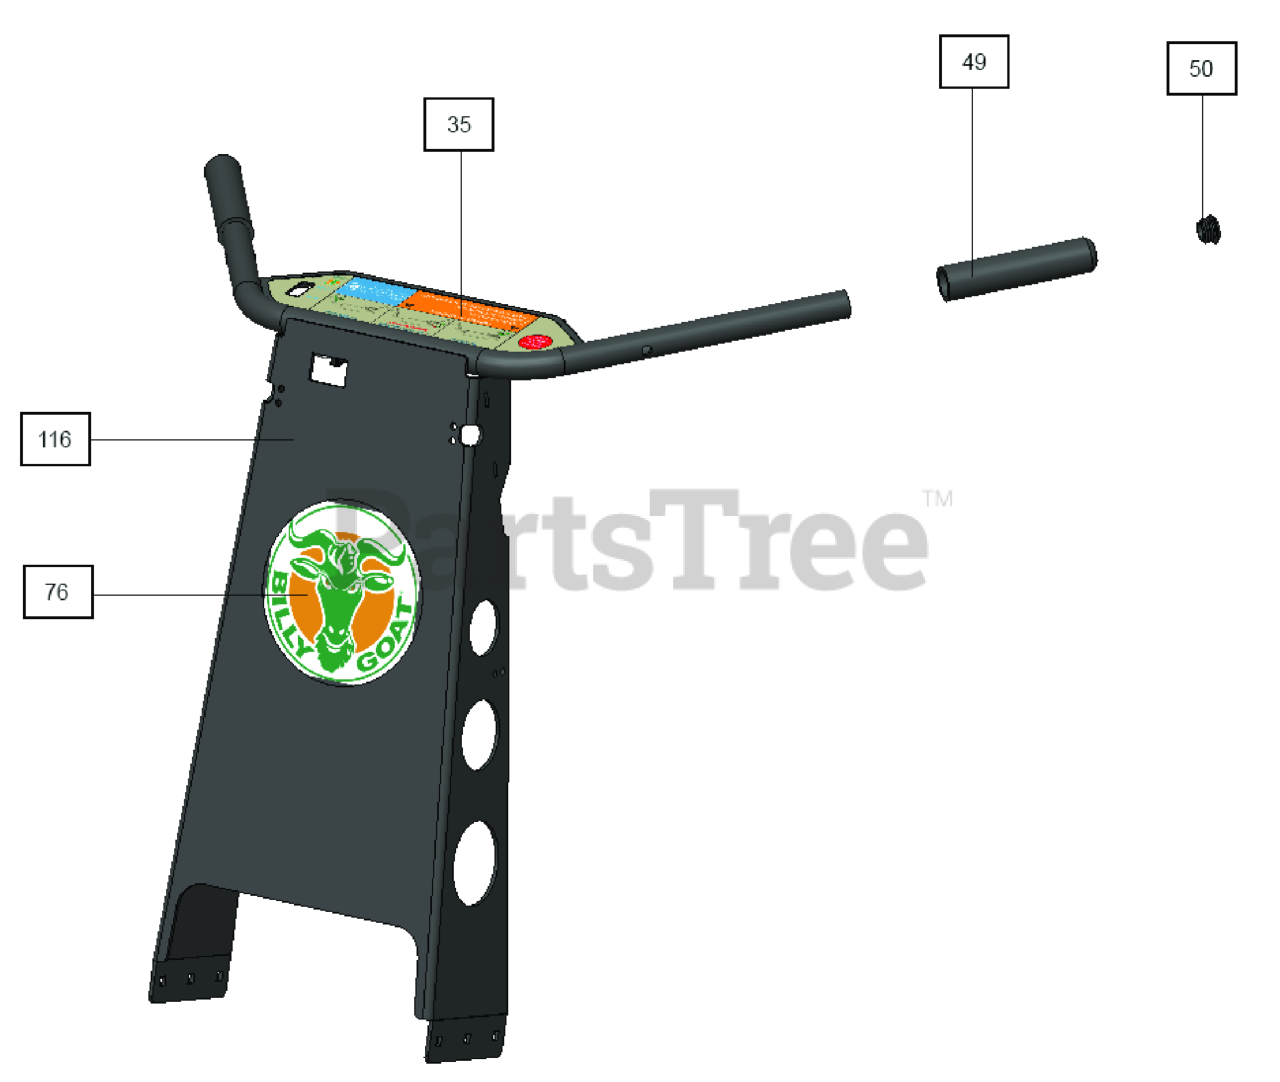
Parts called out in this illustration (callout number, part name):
35	LABEL CONSOLE SC181H
49	GRIP HANDLE
50	PLUG TUBE INSERT 1" OD
76	LABEL LOGO QB
116	HANDLE SC181H WA
